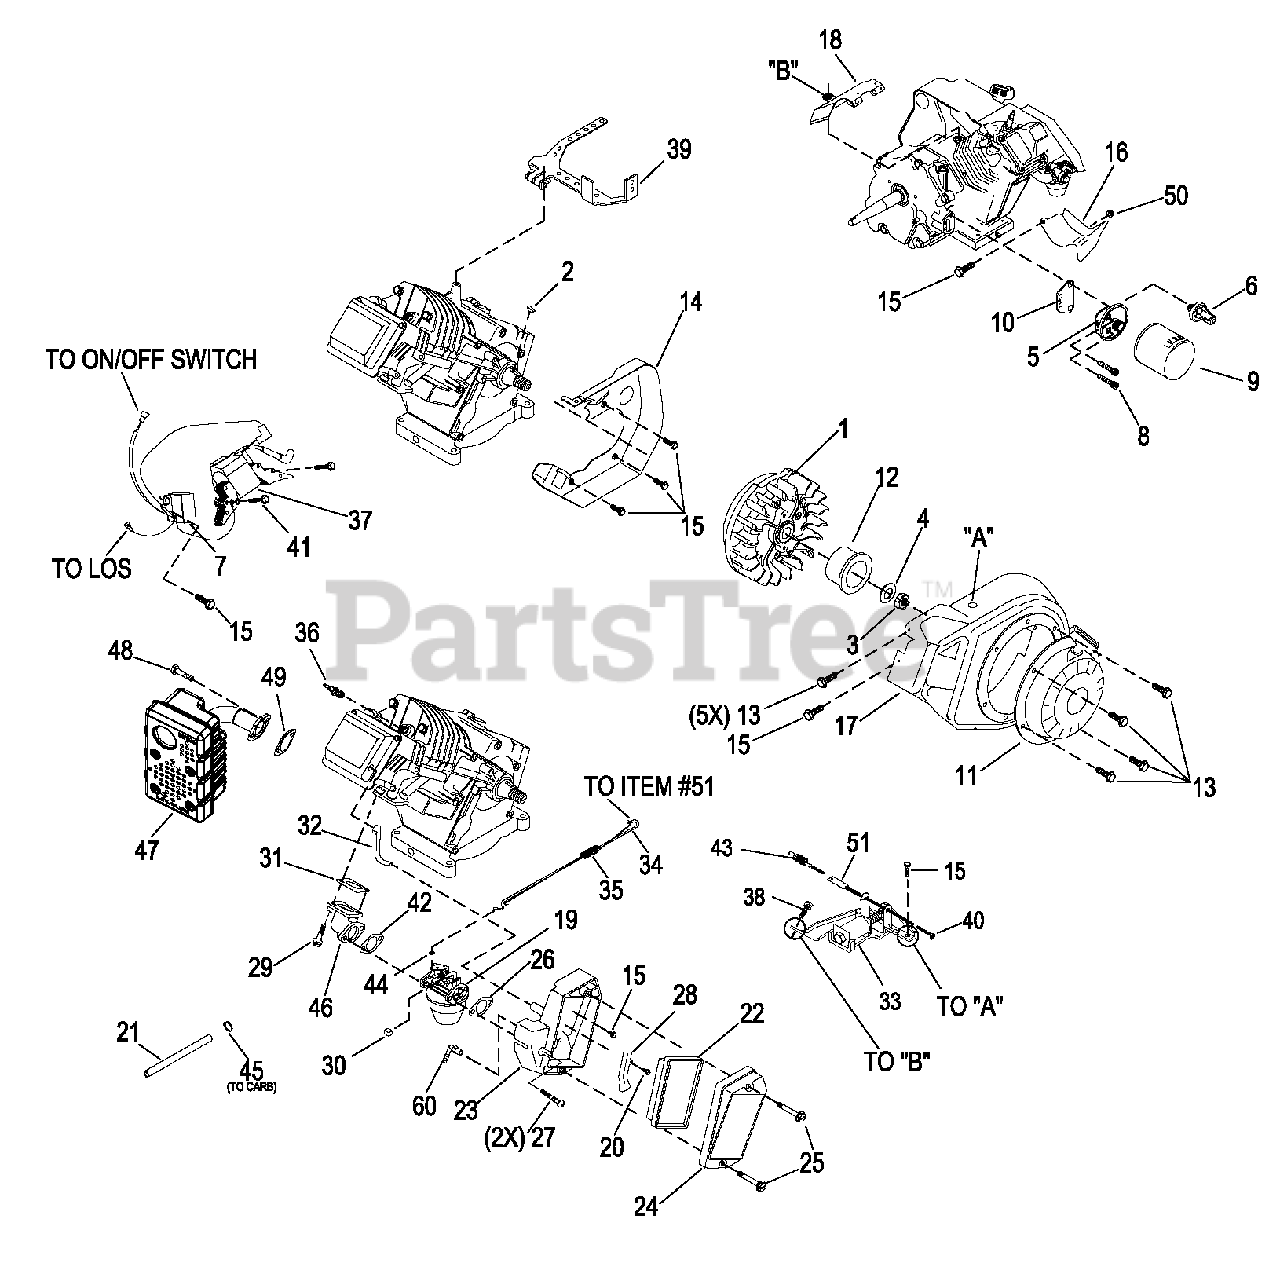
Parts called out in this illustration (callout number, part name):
1	ASSY, FLYWHEEL 29 DEGREE
2	KEY, WOODRUFF 4 X 19 DIAMETER
3	NUT, HEX M16-1.5 G8
4	WASHER, M16 CONICAL
5	ADAPTOR, OIL FILTER GH220
6	OIL PRESSURE SWITCH 5PSI
7	ASSY, LOS MODULE NO LED
8	SCREW, SHC M6-1.0 x 20
9	OIL FILTER BLACK 75mm LONG
10	GASKET, OIL PSI
11	ASSEMBLY, RECOIL STARTER
12	CUP, RECOIL
13	SCREW, HHTT M6-1.0 x 8
14	BACKPLATE, WITH KNOCKOUT GH220
15	SCREW, HHTT M6-1.0 x 10
16	WRAPPER, LOWER GH220
17	BLOWER HOUSING GH220
18	ASSEMBLY, TOP WRAPPER GH220
19	CARB, GH220 WITH CHOKE LEVER
20	SCREW, HHTT M5 - 0.8 X 12 BP
21	HOSE, 1/4" SAE30R11 GREENBAR 14"
22	ELEMENT, AIR CLEANER
23	BASE, AIR CLEANER
24	COVER, AIR CLEANER
25	SCREW, HHSFC M6-1.0 x 31
26	GASKET, CARB / MANIFOLD W/O ADHESIVE
27	BOLT, CARBURETOR MOUNTING
28	COVER, BREATHER CANAL
29	SCREW, HHFC M6-1.0 x 30
30	KNOB, CHOKE LEVER
31	GASKET, MANIFOLD / HEAD
32	HOSE, BREATHER GH220
33	IDLE CONTROL ASSY, GOV SF
34	GOVERNOR ROD
35	ANTI-LASH SPRING
36	SPARK PLUG GAP: 0.030"
37	ASSY, IGNITION COIL ADVANCED NO DIODE
38	SCREW, HHTT M8-1.2 x 16
39	GOVERNOR LEVER
40	NUT, HEX LOCK M5-0.5 NYLON INSERT
41	SCREW, HHTT M6-1.0 x 25 ZINC
42	GASKET, CARBURETOR / AIRBOX
43	SPRING, GOVERNOR
44	WASHER, NYLON 0.12ID x 0.28OD
45	CLAMP, HOSE #5.5
46	INTAKE MANIFOLD
47	MUFFLER, GH220 SIDE-OUT
48	SCREW, SHC M8-1.25 x 20 SEMS
49	GASKET, EXHAUST
50	GROMMET, 9/16" x 1/16" X 7/16"
51	BOLT, GOV ADJ M5
60	BARBED ELBOW, 1/8 NPT X 3/8 NY (MODEL 005929-1 ONLY)
